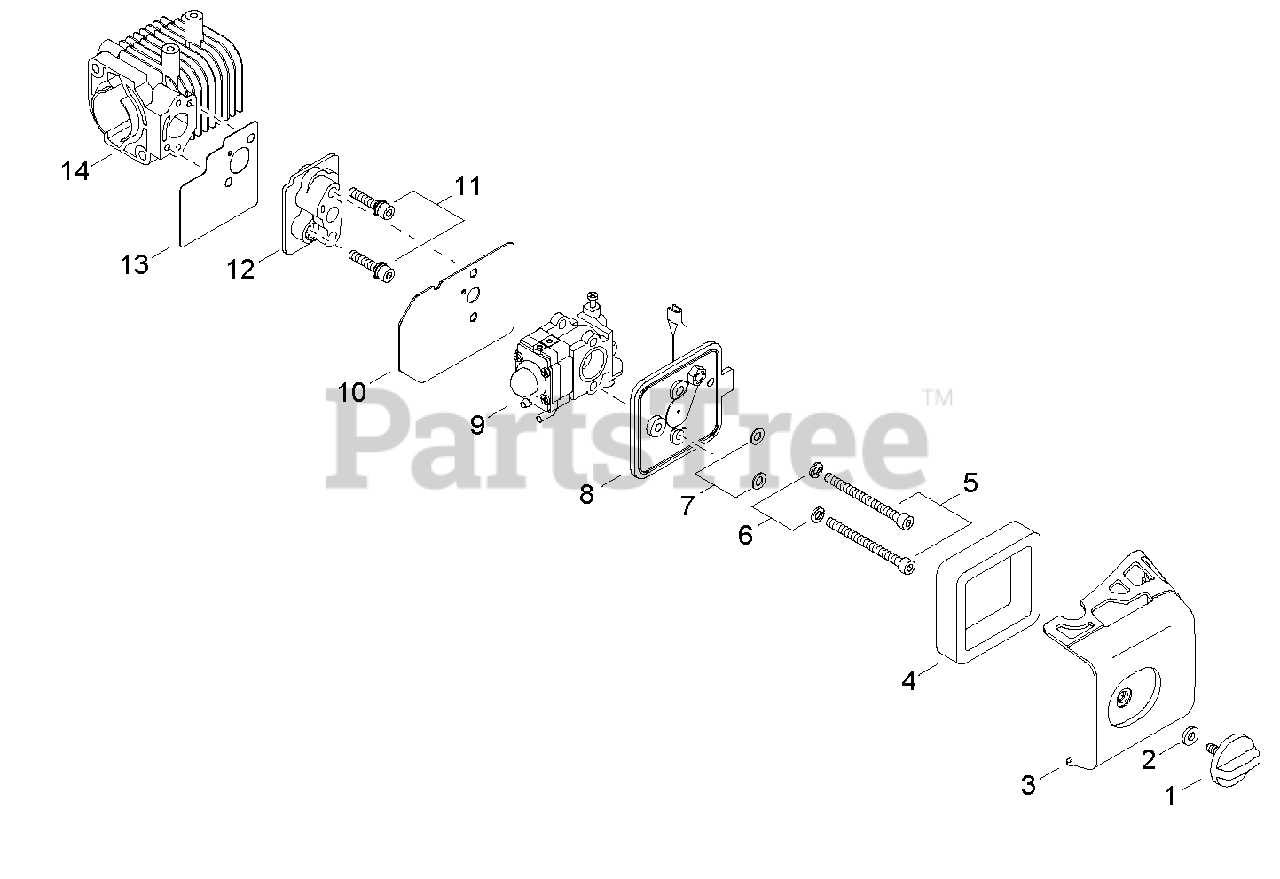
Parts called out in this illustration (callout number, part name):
1	THUMBSCREW
2	WASHER 5
3	COVER, AIR FILTER
4	FILTER, AIR
5	BOLT 5×55
6	WASHER, SPRING 5
7	WASHER, FLAT 5.5×10×0.8
8	CASE ASSY, AIR FILTER
9	CARBURETOR - WYJ-488
10	GASKET, CARBURETOR
11	BOLT M5×30
12	INSULATOR, INTAKE
13	GASKET, INTAKE
14	CYLINDER
